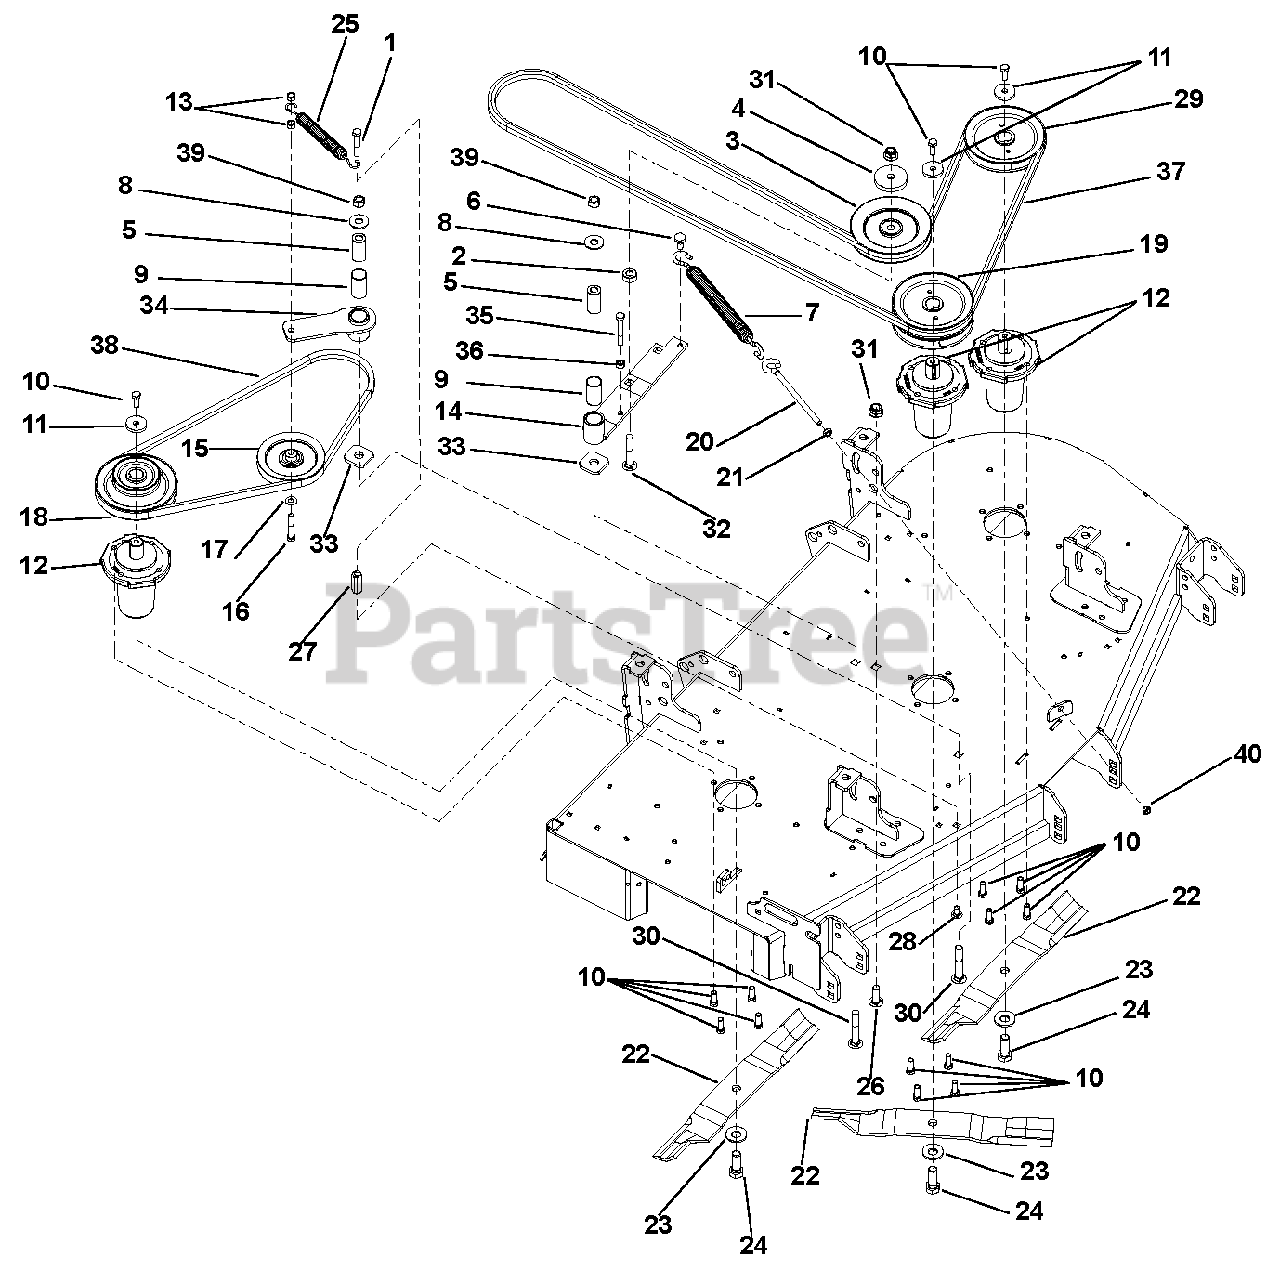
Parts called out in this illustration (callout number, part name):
1	Bolt, Hex .38-16 x 1.75
2	Bushing, Spacer .502 x .997 x .50
3	Sheave, .50" ID x 6.00" OD V-Idler
4	Cap, Idler Bearing Sealing
5	Bushing, Spacer .505/.500 x .999/.996 x 2.05/2.03
6	Bolt, Shoulder EP .38-16 x .30 Hex
7	Spring, Extension (Deck Idler)
8	Washer, Flat Steel .563 x 1.38 x .109
9	Bushing, 1.00 x 1.125 x 1.936
10	Bolt, Hex .38-16 x 1.00
11	Washer, Flat Steel .406 x 1.50 x .245
12	Spindle Assembly
13	Nut, Locking Center .38-16
14	Weldment, Idler Arm
15	Sheave, .38" ID x 5.00" OD V-Idler
16	Bolt, Hex .38-16 x 2.25
17	Washer, Flat Steel .406 x .812 x .065
18	Pulley, Double, 1" ID x 5.75" & 3.50" OD (991079, 095)
19	Pulley, Double, 1" ID x 5.75" OD (991079, 095)
20	Bolt, .38-16 x 5.50 .62 Diameter Eye
21	Nut, Hex, Jam .375-16
22	Blade, 16.19" Mower (991079, 095)
23	Washer, Bellville .63 x 1.625 x .14
24	Bolt, Hex .62-18 x 1.75 Grade 8 (Torque to 115 – 125 ft. lbs., 155 – 169 N-m)
25	Spring, Extension
26	Bolt, Round Head Square Neck .50-13 x 1.5, Full Thread
27	Nut, Coupling .375-16 x 1.75
28	Bolt, Round Head Square Neck .38-16 x 1.00
29	Pulley, V, 1" ID x 5.75" OD (991079, 095)
30	Bolt, Round Head Square Neck .50-13 x 3.25 G5YZ
31	Nut, .50-13 Nyloc Flange
32	Bolt, Round Head Square Neck .50-13 x 3.00
33	Washer, Flat .640 x 1.75 x .250
34	Weldment, Idler Arm
35	Bolt, Hex .38-16 x 2.75
36	Nut, Hex .38-16
37	Belt, BB 118.00 Wrapped Hex (991079, 095)
38	Belt, B 51.18 Raw Cogged (991079, 095)
39	Nut, Locking Center .50-13
40	Nut, Lock Center Jam .375-16
